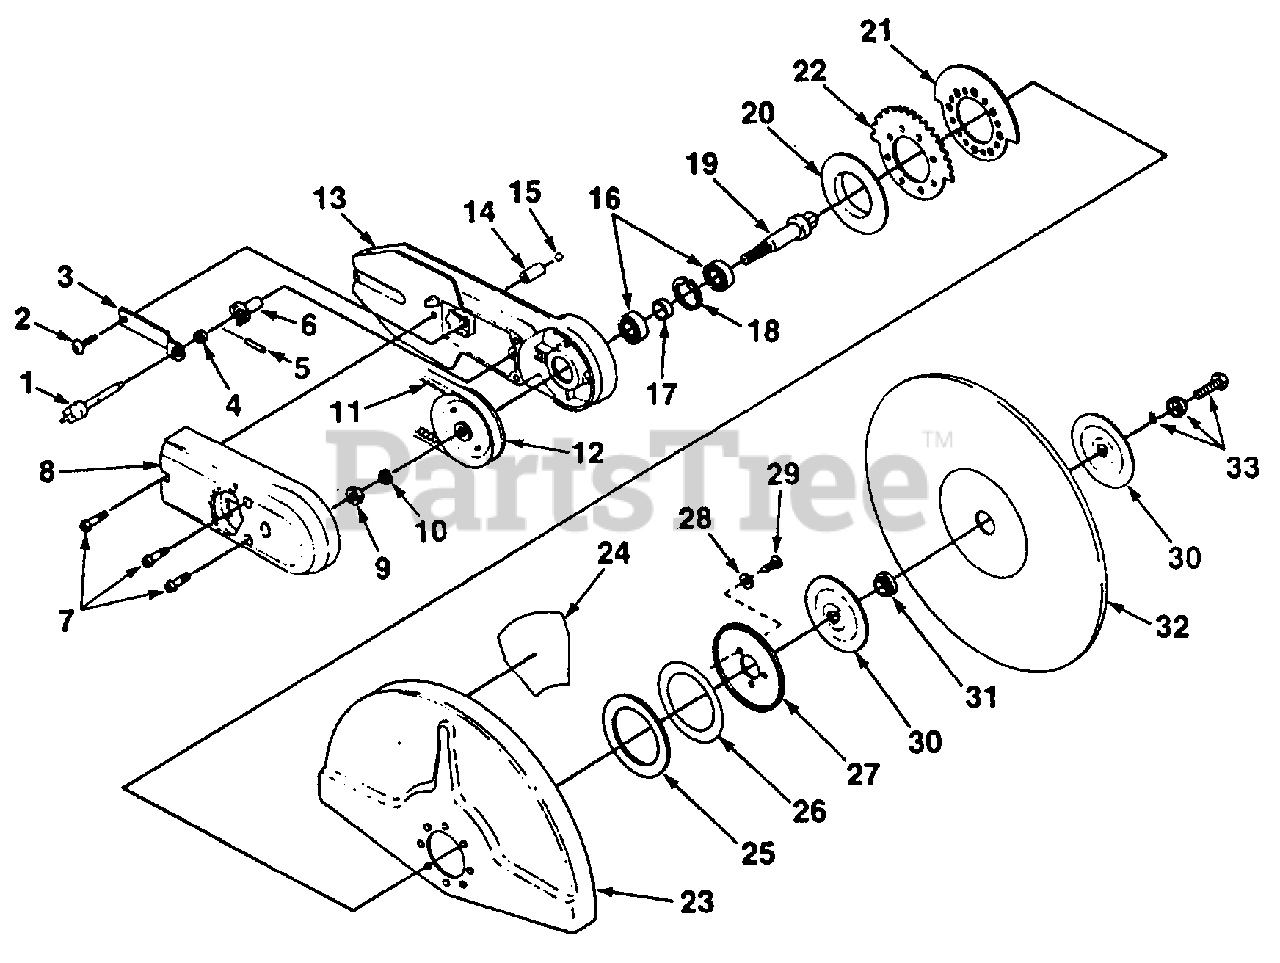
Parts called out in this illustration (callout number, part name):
1	KNOB & PIN
2	SCREW-Truss Hd. (10-24 X 1/2")
3	PLATE-Spring
4	SPACER-Adjusting Pin
6	SLEEVE-Cam
7	SCREW-Round Hd. (10-24 X 23/32")
8	BELT-Cover
9	NUT-Hex
10	WASHER-Lock (7/16)
11	BELT-V-Drive
12	PULLEY & HUB
13	ARM-Wheel
14	SNUBBER
15	STEEL BALL
16	BEARING-Ball
17	SPACER-Bearing
18	RING-Retaining
19	SHAFT-Wheel
20	COLLAR-Wheel Guard
21	PAD-Adjuster
22	DETENT-Adjuster
23	WHEEL GUARD & DECAL / 12"
23	WHEEL GUARD & DECAL / 14"
24	DECAL-Caution
25	WASHER-Rubber
27	WASHER-Spring
28	WASHER (#12 - 11/16)
29	SCREW-Truss Hd. (10-24 X 1/2")
30	FLANGE-Wheel
31	SPACER (1")
32	WHEEL
33	BOLT & WASHER
